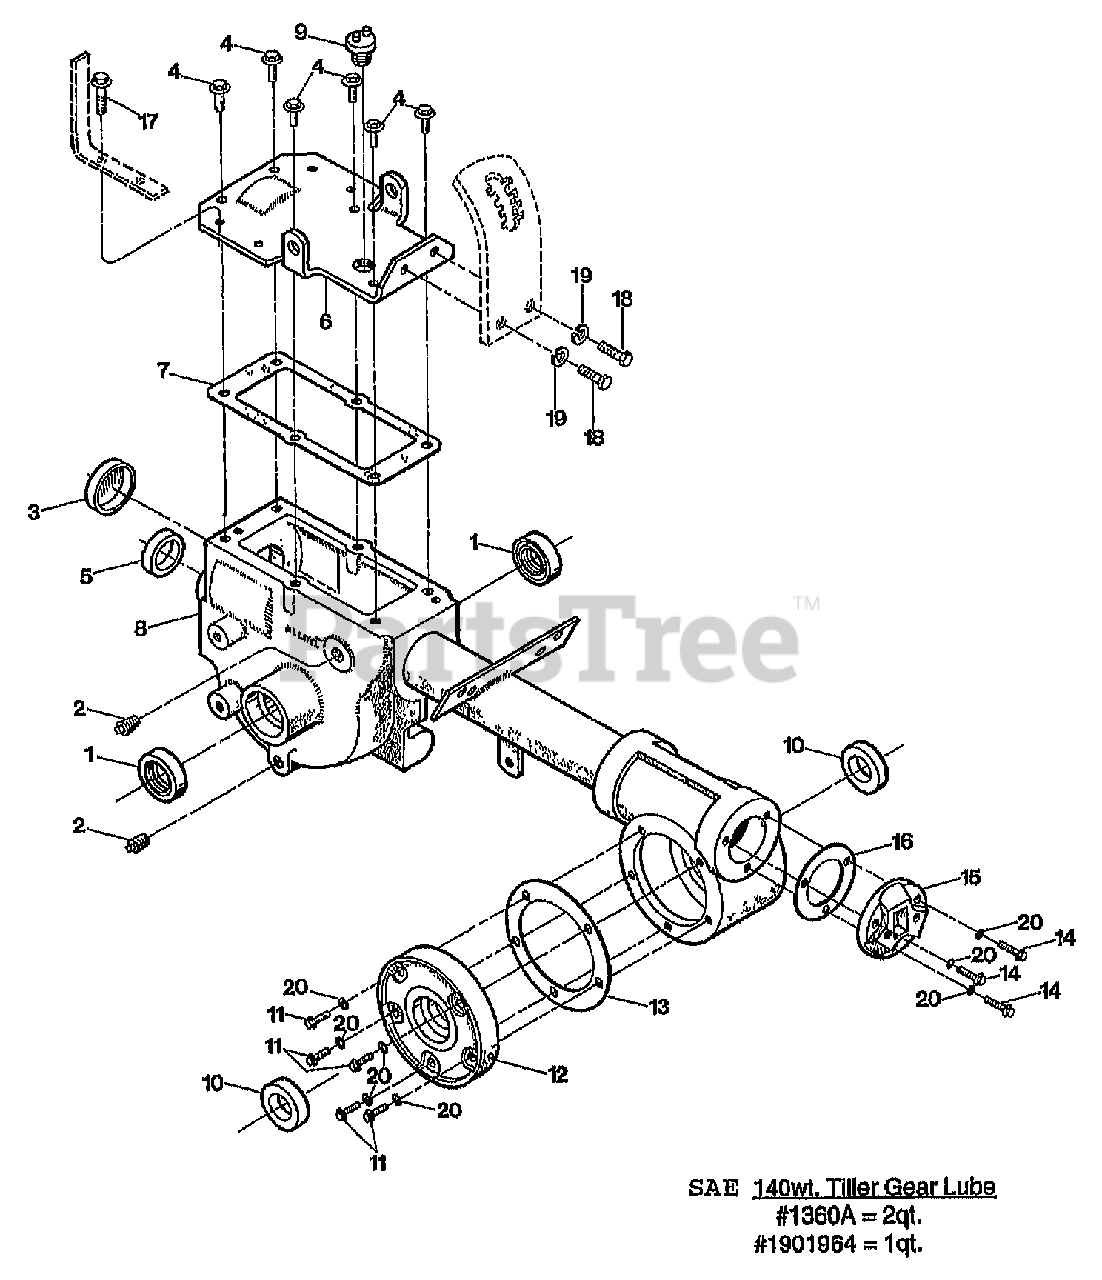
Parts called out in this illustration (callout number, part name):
1	SEAL-OIL-DOUBLE LIP, WHEEL SHAFT, RH & LH
2	PLUG-PIPE 1/4 NPT, OIL LEVEL HOLE & GEAR OIL DRAIN HOLE.
3	SEAL-BORE TRANSMISSION
4	SCR-HFLK 5/16-18X.75 ZP
5	SEAL-PINION SHAFT PT/85030/00
6	KIT-COVER TRANS W/HDW (INCL. FOUR NO. 17 & TWO EA. OF NO. 18 & 19)
7	GASKET-TRANS COVER
8	ASSM-TRANS A-UNIT JR W/UP
9	PLUG-OIL FILL 3/4-10 FOR GEAR OIL FILL HOLE ON TRANSMISSION COVER.
10	SEAL-TILLER SHAFT TILLER SHAFT RH & LH
11	SCR-HH 1/4-20X.625
12	COVER-TILLER HSG MACH TILLER HOUSING LH ( INCL. 5 SCREWS NO.11)
13	GASKET-TILLER COVER .010" THICK (FITS ALL COVERS)
14	SCR-HFLK 1/4-20X.875
15	CAP-REAR #1115
16	GASKET-BRG COVER
17	SCR-HFLK 5/16-18X1.00 ZP
18	SCR-HH 3/8-16X.75 G5 ZP
19	WASHER-LK .375 @ DEPL
20	WASHER, NYLON
